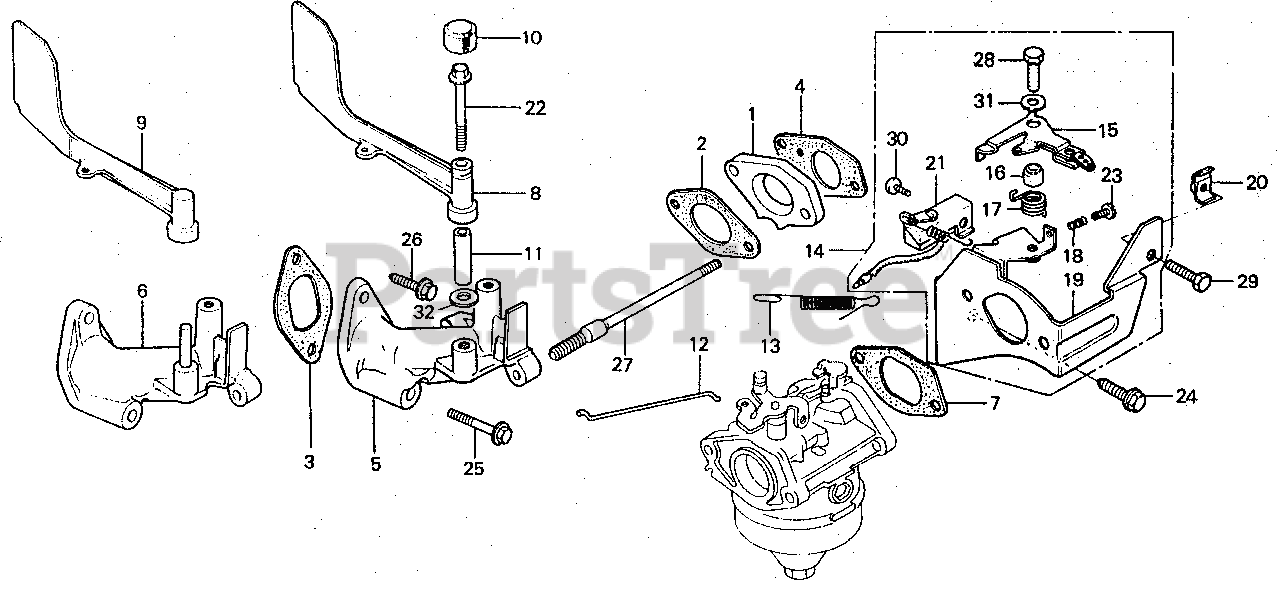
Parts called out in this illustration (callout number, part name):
1	INSULATOR, CARBURETOR
2	GASKET, INSULATOR
3	GASKET, MANIFOLD
4	GASKET, CARBURETOR
6	MANIFOLD, IN.
6	MANIFOLD, IN. (NOT AVAILABLE)
7	GASKET, AIR CLEANER
9	FLUTTER, GOVERNOR
12	ROD, GOVERNOR (NOT AVAILABLE)
13	SPRING, GOVERNOR
14	CONTROL ASSY.
15	LEVER, CONTROL
16	COLLAR, LEVER SETTING
17	SPRING, RETURN
18	SPRING, STOPPER LEVER
19	STAY, CLEANER CASE
20	HOLDER, WIRE
21	SWITCH ASSY., ENGINE STOP
23	BOLT (4X20)
24	BOLT, FLANGE (6X12) (CT200)
25	BOLT, FLANGE (6X50)
26	BOLT, FLANGE (6X20) (CT200)
27	BOLT, STUD (6X141) (NOT AVAILABLE)
28	BOLT, HEX. (5X20)
29	BOLT, HEX. (6X14)
30	SCREW, PAN (4X8)
31	WASHER, PLAIN (5MM)
